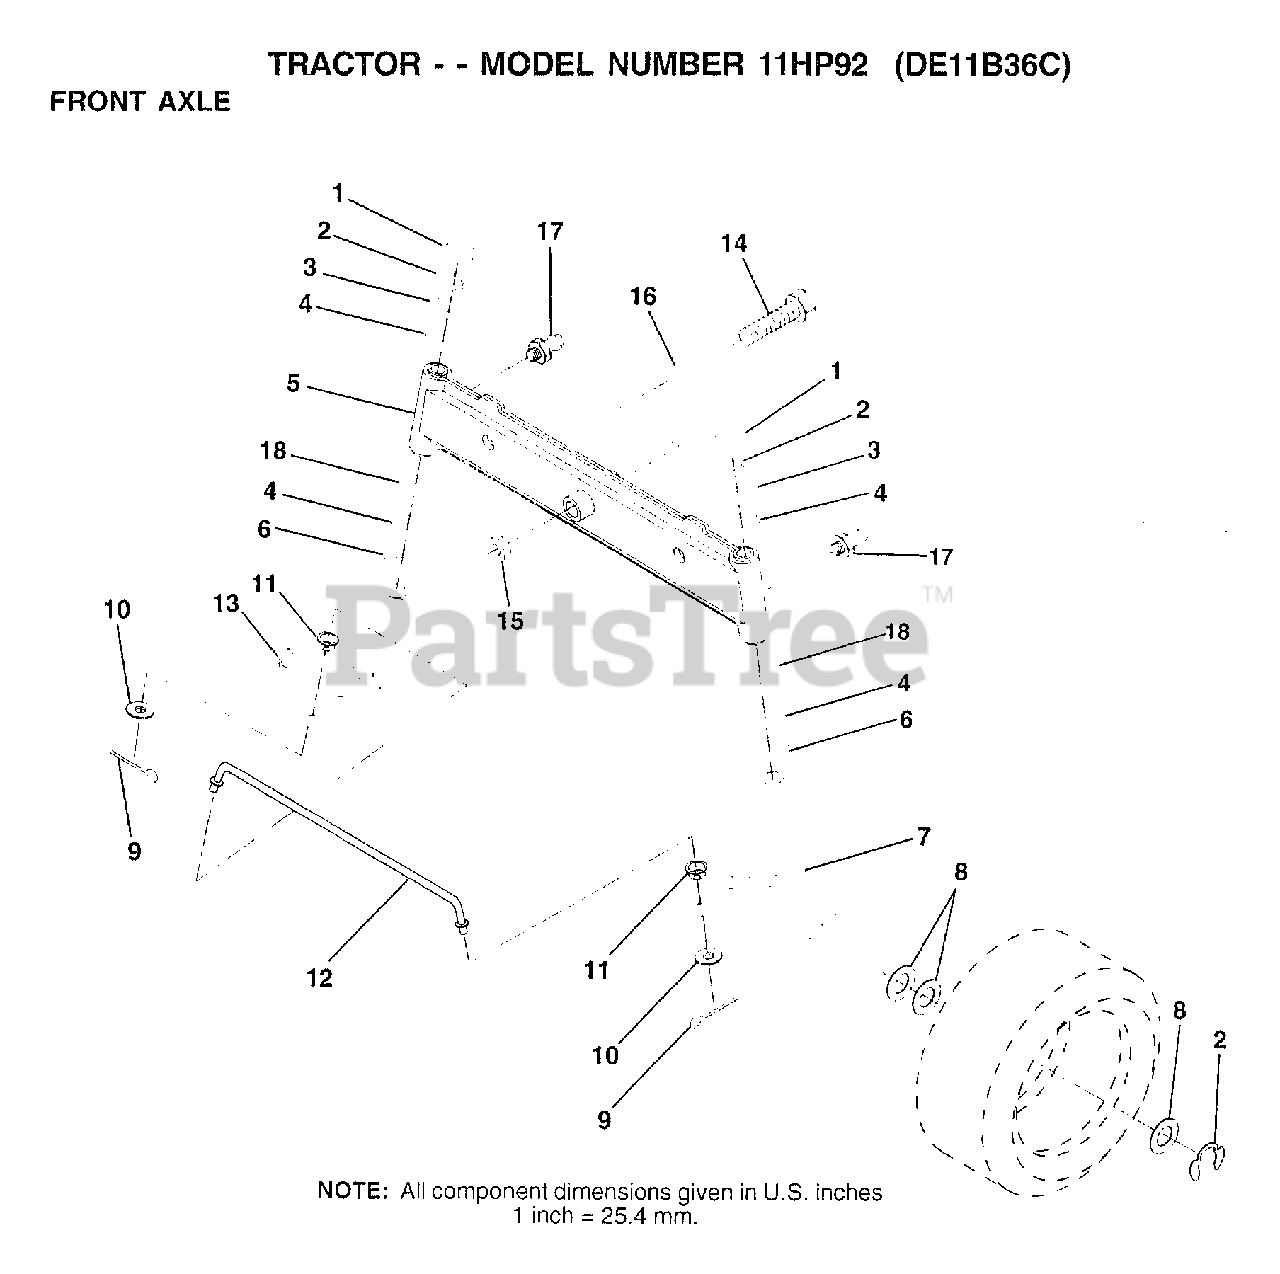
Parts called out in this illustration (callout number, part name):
1	CAP
2	RING
3	WASHER
4	COL. SRTG. BEAR.
5	AXLE ASM FRONT
6	WASHER .T
7	SPINDLE.ASSY.RH
8	WASHER
9	COTTER PIN
10	WASHER
11	BUSHING.DRAGLINK
12	TIE ROD
13	SPINDLE.ASSY.LH
14	BOLT HEX 5/8-11
15	"NUT-LOC,FLANGE LT"
16	BEARING
17	ZERK M
18	WASHER
